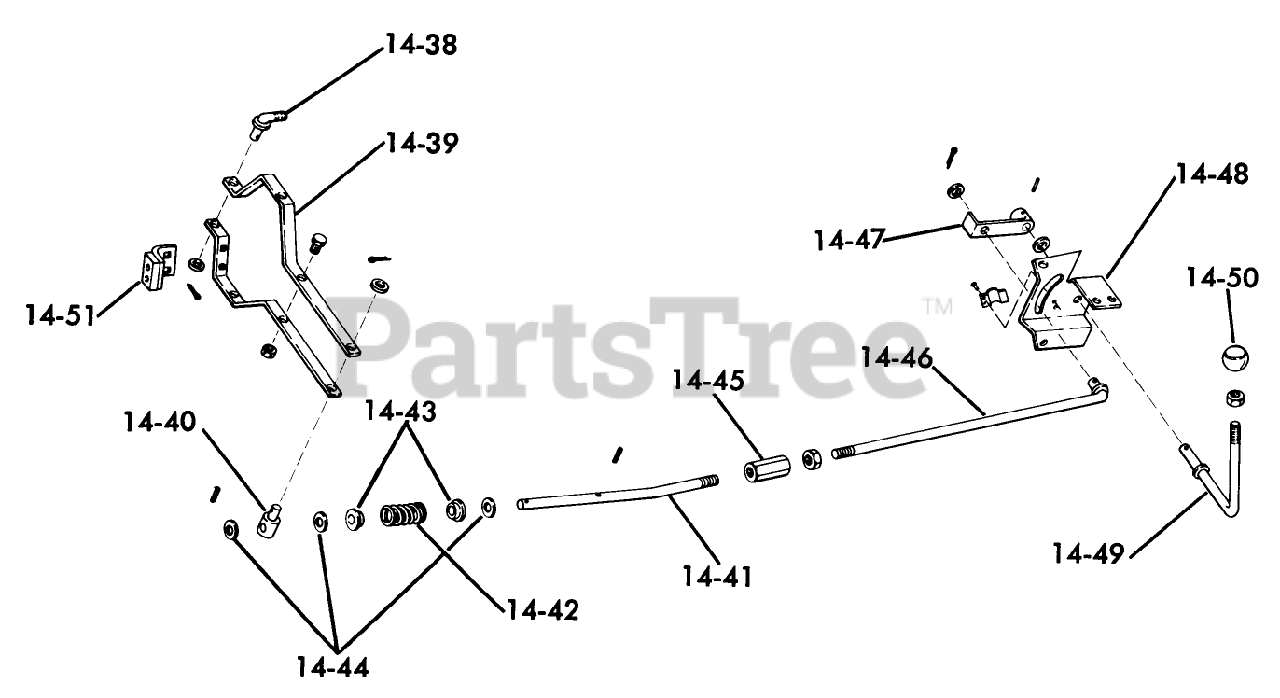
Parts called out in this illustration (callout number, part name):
14-38	WASHER
14-40	TRUNION
14-41	PIN-ROLL
14-47	ARM CLUTCH ENGAGE
14-48	Pop Rivet-1/8 x .294
14-49	ASSY CLUTCH HANDLE
14-49	Spirol Pin
14-51	RIVET-BRASS
14-52	SWITCH-CLUTCH
14-52	CLIP-SWITCH
14-53	LOCKWASHER
